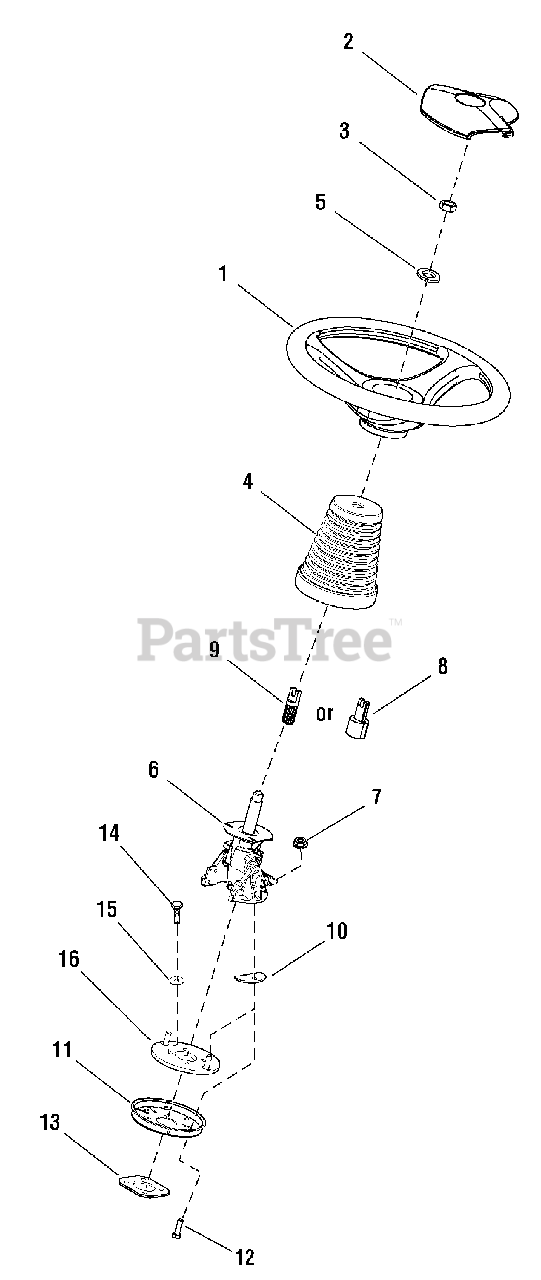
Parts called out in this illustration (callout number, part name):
1	STEERING WHEEL
2	CAP, Steering Wheel
3	NUT, Hex, 5/8-16
5	WASHER, 5/8
6	TILT STEERING ASSEMBLY
7	NUT, Keps, 5/16-1/8
8	ADAPTER, Tilt Steering
9	ADAPTER, Tilt Steering
10	SPACER, Tilt Steering
11	MOUNTING PLATE
12	CAPSCREW, Hex, 5/16-18 x 1
13	MOUNTING PLATE
14	SCREW, M6 x 1 x 30
15	WASHER, Lock, 1/4
16	MOUNTING PLATE
